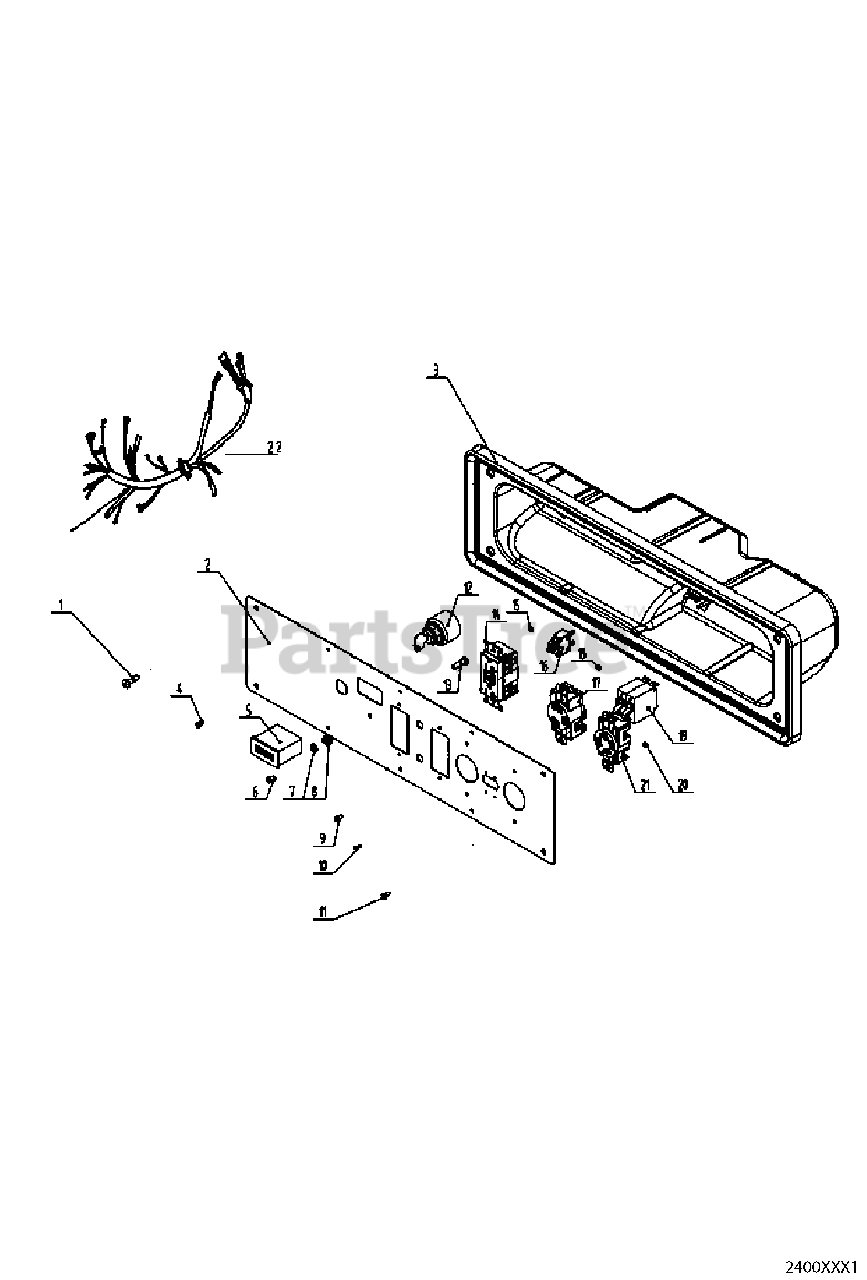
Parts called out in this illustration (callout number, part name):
2	CONTROL PANEL CP
6	BOLT
8	SUS FLANGE NUT
9	BOLT
11	BOLT
14	AC CONCENT,GFCI
15	NUT FLANGE
18	NUT FLANGE
20	NUT FLANGE
